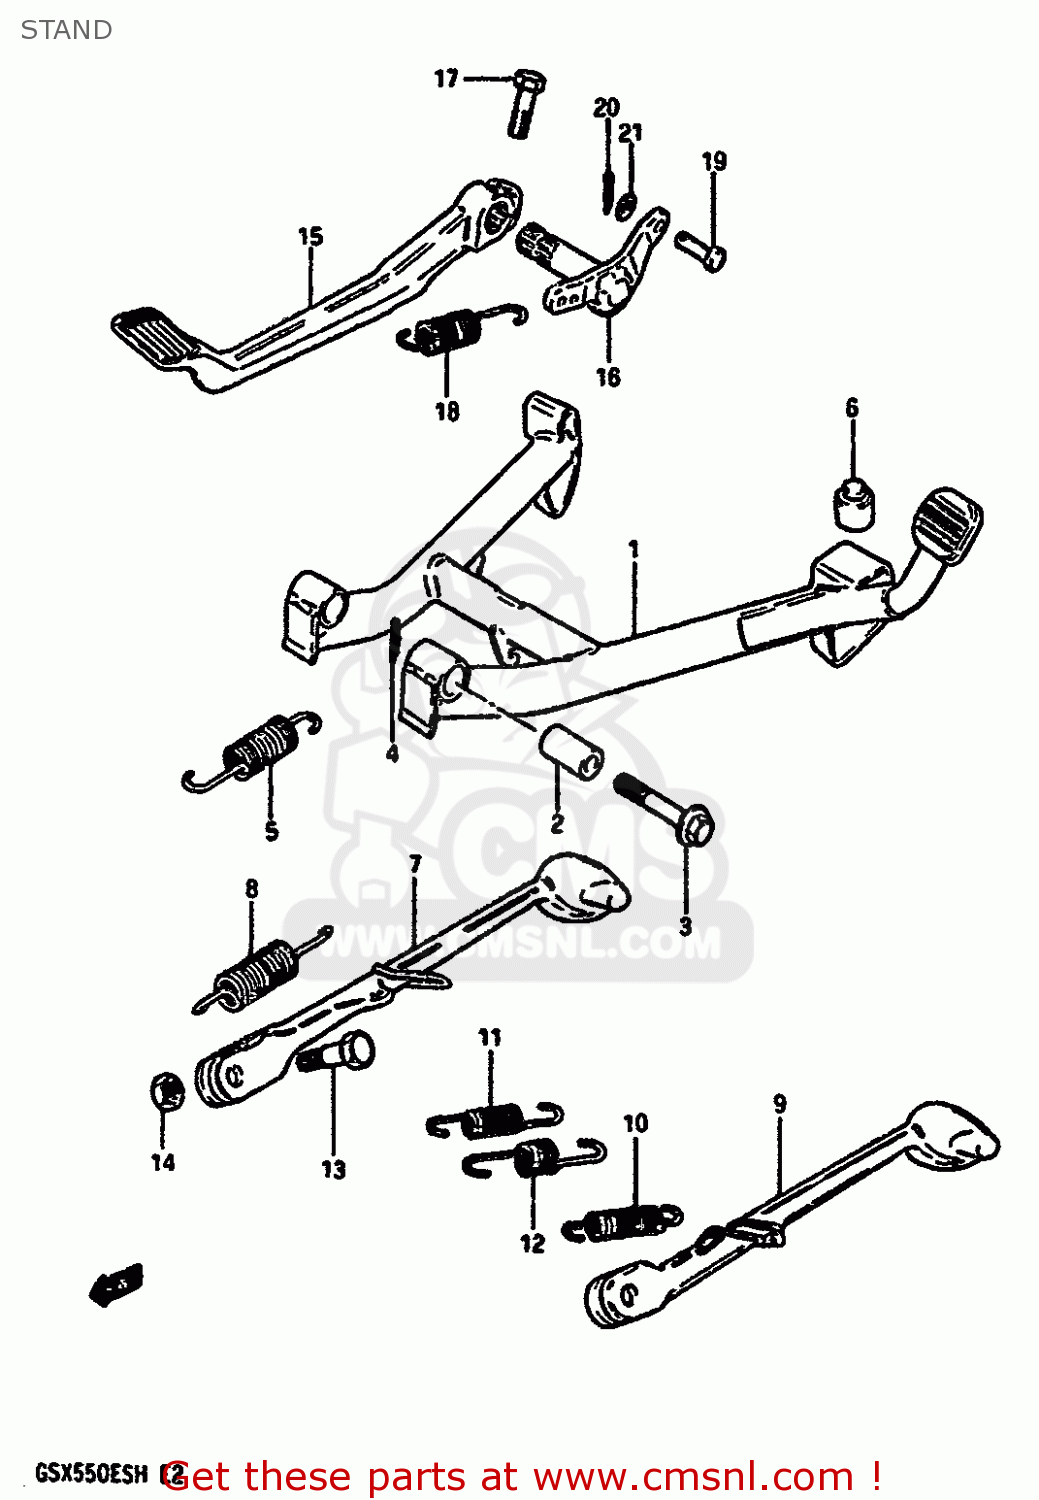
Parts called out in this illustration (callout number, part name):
1	STAND,CENTER
2	SPACER (10.5X16X31.8)
3	BOLT 10X50
4	CLIP
5	SPRING
6	CUSHION
7	STAND,SIDE
8	SPRING
9	STAND, PROP (SILVER)
10	SPRING
11	SPRING, INNER
12	SPRING, OUTER
13	BOLT L:30
14	NUTM10X1.25X8
15	PEDAL,BRAKE
16	ARM,BRAKE PEDAL ROD
17	BOLT
18	SPRING
19	PIN
20	PIN
21	WASHER
